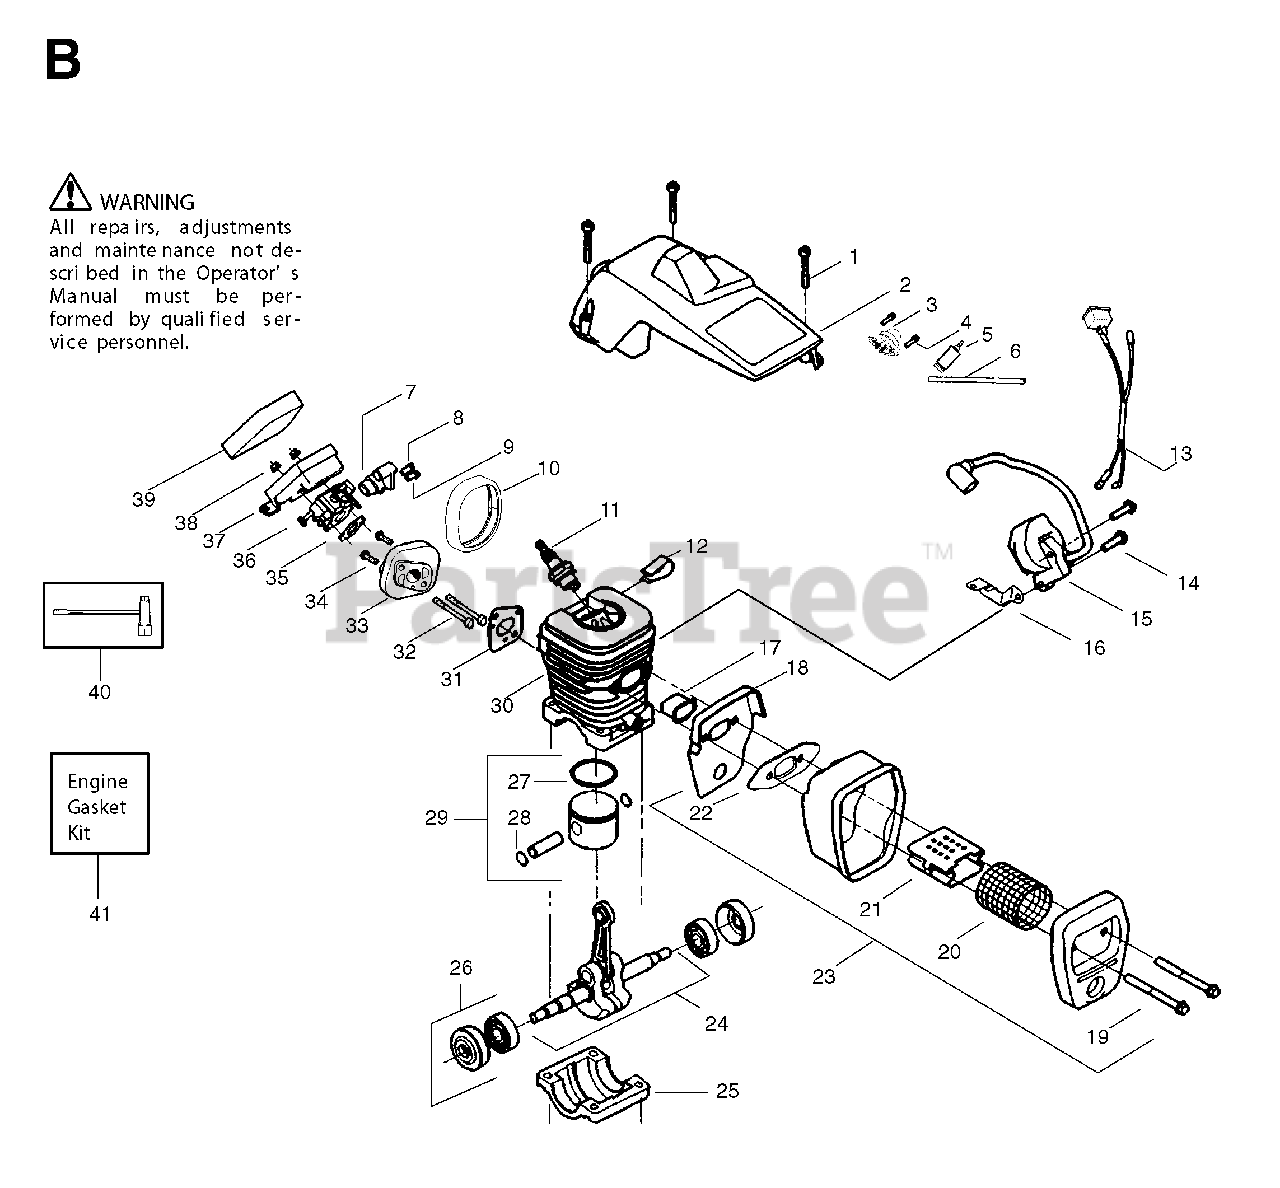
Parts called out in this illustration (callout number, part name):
5	FUEL PICK-UP ASSY
6	KIT-LINE
7	GROMMET-CARB ADJUST.
10	SEAL
11	SPARK PLUG RCJ7Y
13	WIRE HARNESS ASS'Y
15	IGNITION MODULE
16	GROUND STRAP
17	HEAT INSULATOR
21	FLAME PROTECTION
23	MUFFLER
24	CRANKSHAFT
26	ASSY-BEARING & SEAL
27	PISTON RING 36
28	C-CLIP,PSTN PIN 36/41
31	GASKET-CARB ADAPTER
33	PARTITION
34	SCREW - SHROUD
35	GASKET
36	CARBURETOR
37	AIR FILTER HOUSING
39	AIR FILTER
40	SCRENCH
5300874-22	UK/F/D/ESP
5300874-24	DK/FIN/N/S
5300874-25	GRE/PT/NL/I
